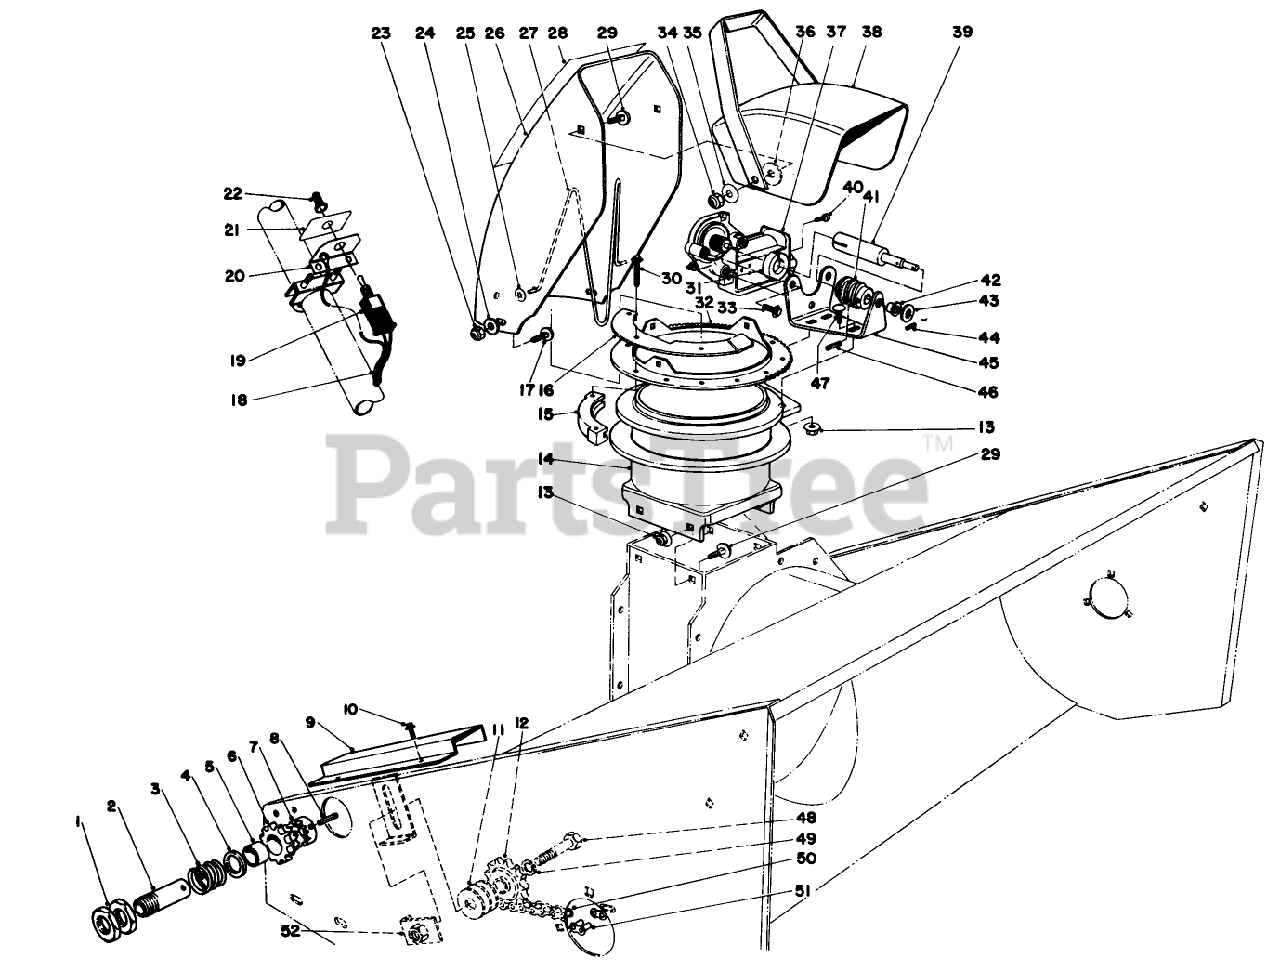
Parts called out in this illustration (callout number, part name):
1	THIN NUT
2	Clutch Sleeve
3	Spring Compression
6	Clutch Sprocket
7	Clutch Collar
8	PIN-ROLL
10	SCREW-HWHTF
11	WASHER-FLAT
12	IDLER SPRKT (60016)
13	NUT-HHF, WHIZ
15	RETAINER-CHUTE
17	SCREW-CARR
19	Toggle Switch
20	Toggle Switch Mount
22	BOOT-SWITCH
23	NUT-LOCK, NI
24	WASHER-PLAIN
25	NUT-PUSH
27	WIRE-CHUTE
29	SCREW-CARR
30	SCREW-SPECIAL
33	SCREW-HHF
34	NUT-LOCK, CONE
35	WASHER-BELLEVILLE
36	WASHER-RUBBER
38	Deflector
40	SCREW-HSH
41	GEAR-WORM, CHUTE
42	FLANGE BSHG #FF-310-3
43	WASHER-FLAT
44	3/32 X 9/16 ROLL PIN
46	PIN-SPRING
47	SCREW-HH
48	SCREW-HH
49	WASHER-LOCK
51	LINK-CHAIN
